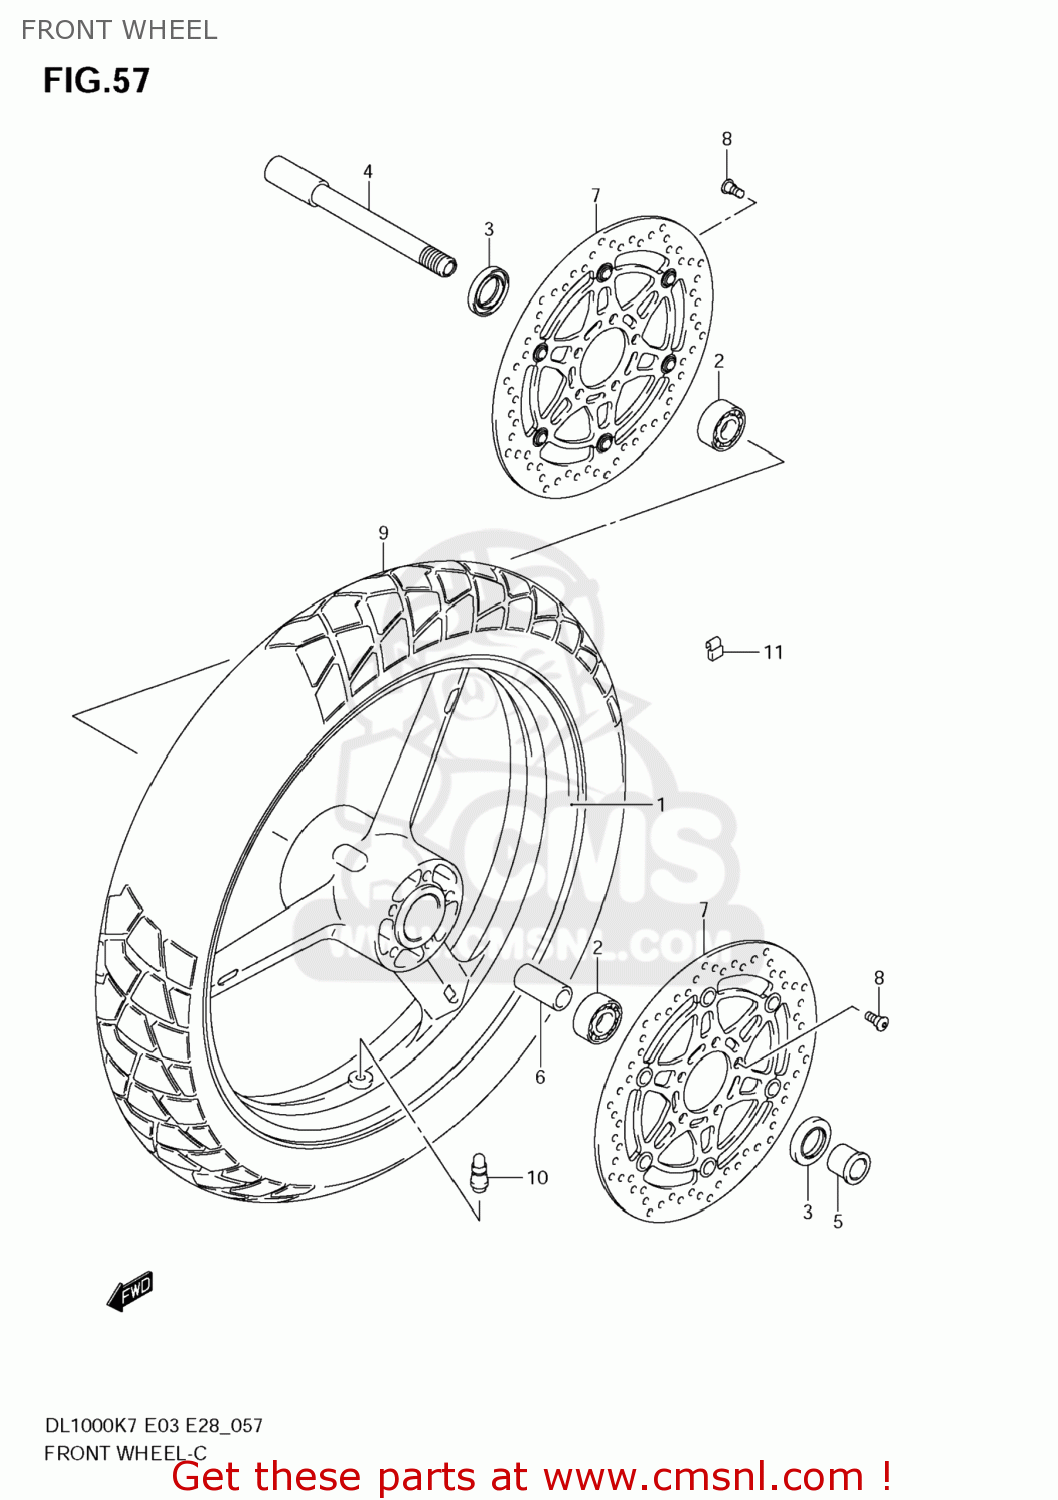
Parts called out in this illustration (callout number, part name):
1	WHEEL,FR(19M/CXMT2.50)
2	BEARING
3	SEAL,OIL(28X47X7)
4	AXLE,FR
5	SPACER,FR AXLE
6	SPACER(20.5X28X88)
7	DISC,FR BRAKE
8	BOLT(8X21)
9	TIRE,FR(110/80R19M/C 59H)
10	VALVE ASSY,WHEEL RIM(TR412)
11	WEIGHT,WHEEL BALANCE 10G
